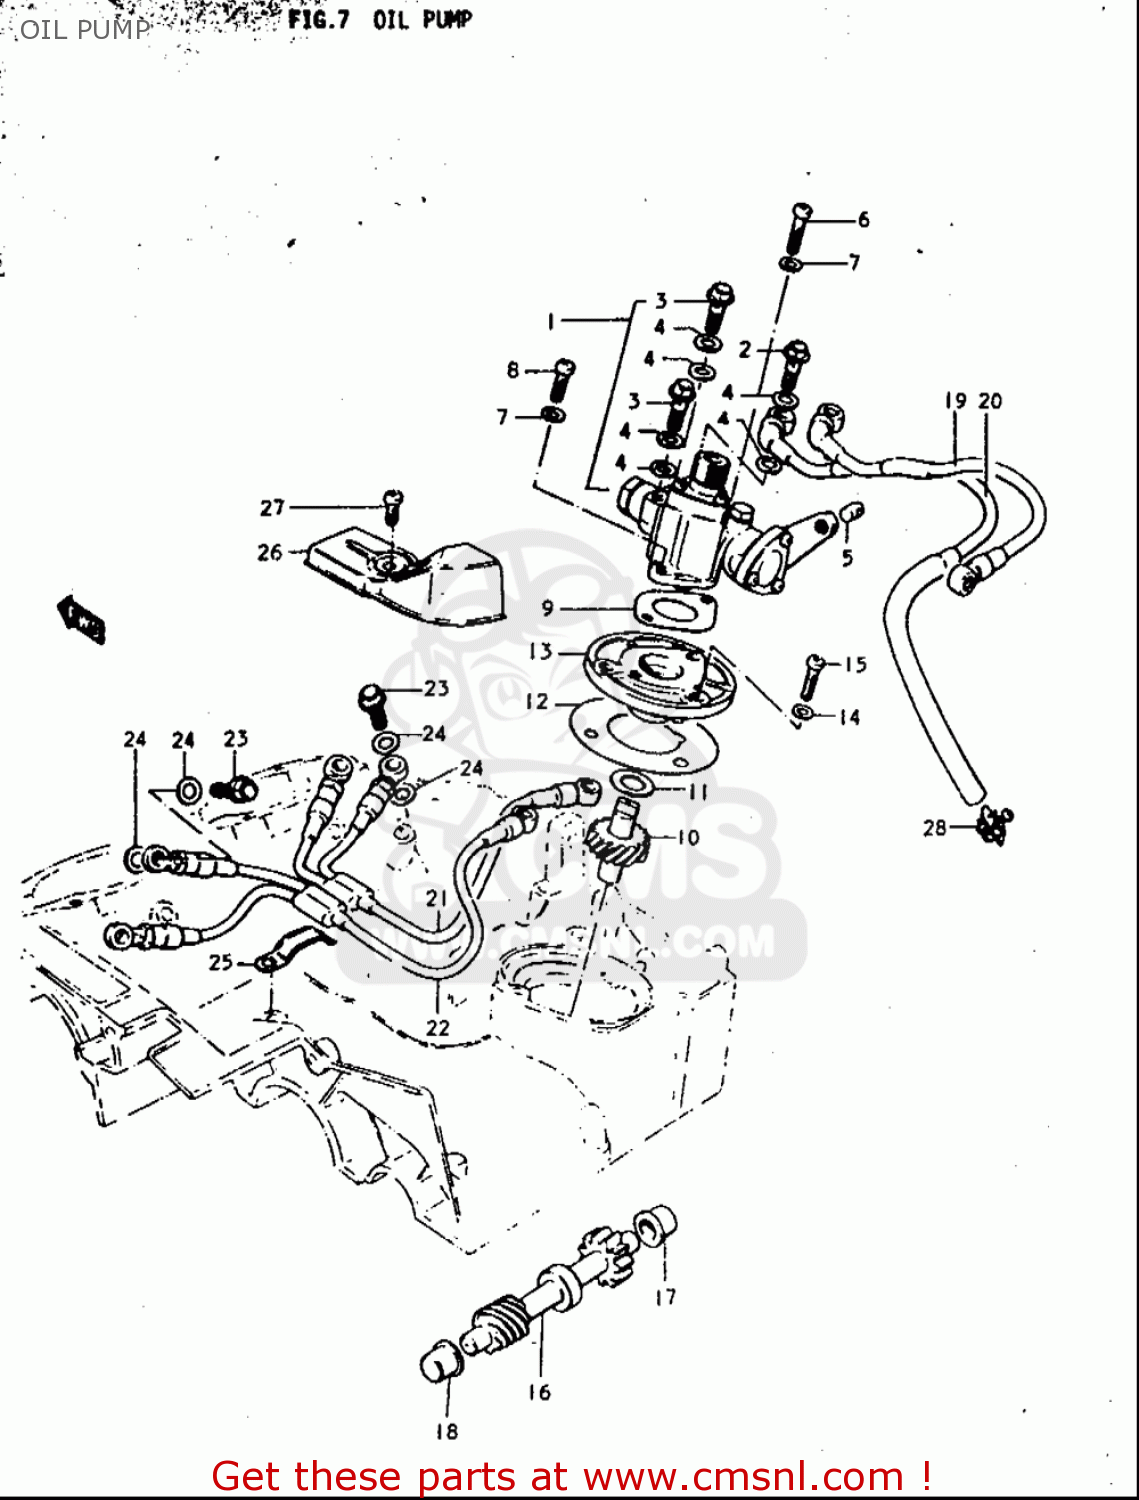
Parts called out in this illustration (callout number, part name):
2	UNION BOLT
3	UNION
4	GASKET(6.2X11X1).2 (NAS)
5	TERMINAL, CABLE
7	WASHER
8	SCREW
11	SHIM(10X20X1)
12	GASKET,OIL PUMP GEAR CASE (MCA)
14	WASHER
23	UNION BOLT
24	GASKET(6.2X11X1).2 (NAS)
25	CLAMP
28	CLAMP
